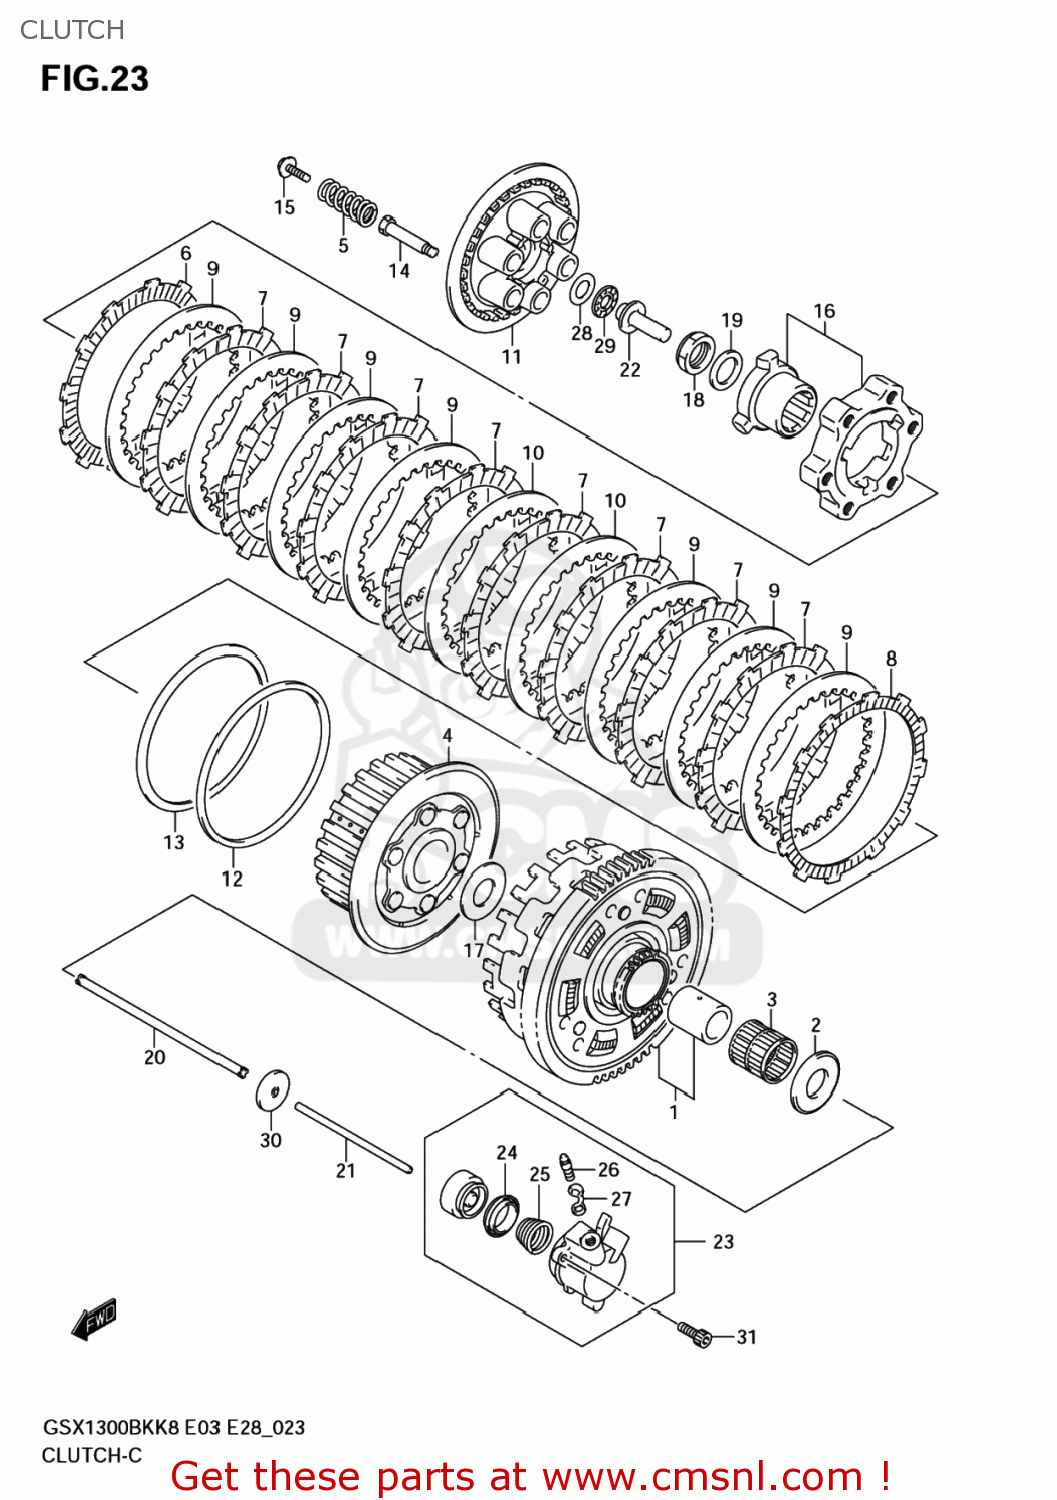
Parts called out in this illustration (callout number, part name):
1	GEAR ASSY,PRI DRIVEN
2	WASHER(25X54X2.4)
3	BEARING(35X40X39.8)
4	HUB,CLUTCH SLEEVE
5	SPRING,CLUTCH
6	PLATE,CLUTCH DRIVE NO.2 (NAS)
7	PLATE,CLUTCH DRIVE NO.1 (NAS)
8	PLATE,CLUTCH DRIVE NO.3 (NAS)
9	PLATE,CLUTCH DRIVEN NO.1(T:2.0 (NAS)
10	PLATE,CLUTCH DRIVEN NO.2(T:2.3 (NAS)
11	DISC,CLUTCH PRESSURE
12	SEAT,WAVE WASHER
13	WASHER,CLUTCH PLATE WAVE
14	BOLT,CLUTCH SP
15	BOLT,CLUTCH SPRING
16	CAM SET,CLUTCH
17	WASHER(25X50X2.5)
18	NUT
19	WASHER
20	ROD,CLUTCH
21	ROD,CLUTCH PUSH,L
22	PIECE,CLUTCH PUSH
23	CYLINDER,CLUTCH RELEASE
24	CUP
25	SPRING
26	BLEEDER
27	CAP,BLEEDER
28	WASHER(15.5X28X1)
29	BEARING(15X28X2)
30	SEAL,OIL(6X34X5.5)
31	BOLT
